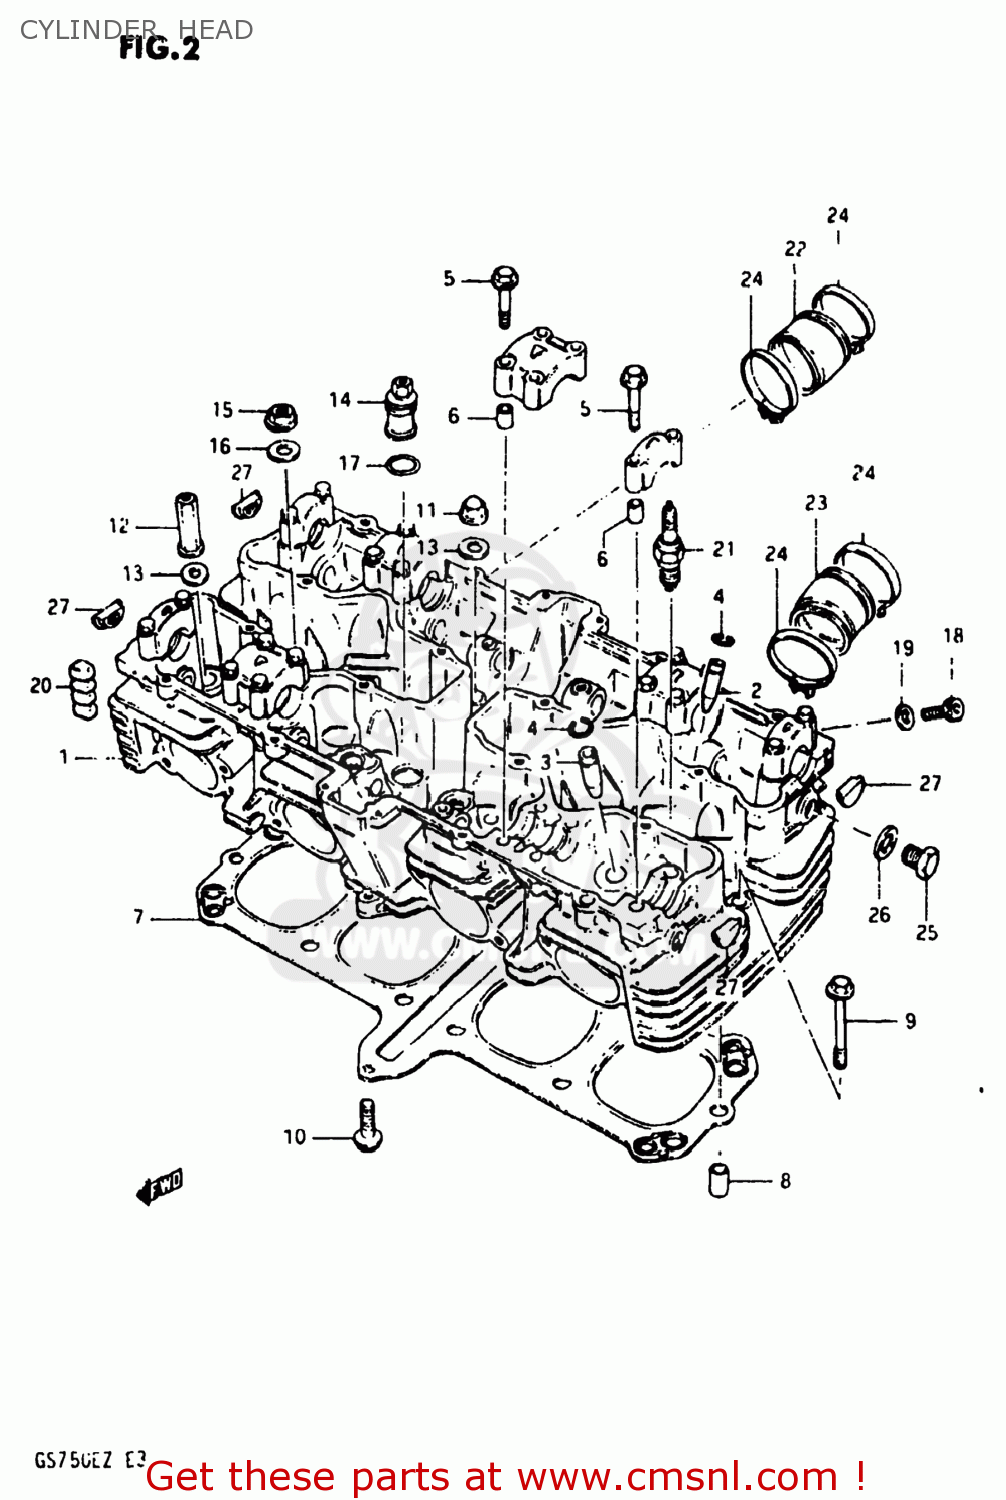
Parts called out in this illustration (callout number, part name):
1	HEAD ASSEMBLY,CYLINDER
2	GUIDE,INTAKE VALVE
3	GUIDE,INTAKE VALVE
4	RING,SNAP
5	BOLT(6X39)
6	PIN(6.2X8X11)
7	GASKET,CYLINDER HEAD (MCA)
8	PIN
9	BOLT
10	BOLT
11	NUT
12	NUT
13	GASKET (NAS)
14	NUT,CYLINDER HEAD SEAL
15	NUT
16	WASHER(10.5X22X2.3)
17	O RING(D:2.4,ID:16.8)
18	BOLT
19	GASKET(5.3X9.3X1.2) (NAS)
20	PAD,CYLINDER
21	SPARK PLUG D8EA
22	PIPE,INTAKE,R
23	PIPE,INTAKE
24	CLAMP
25	PLUG (14X12)
26	GASKET(14X19.2X2) (NAS)
27	PLUG
